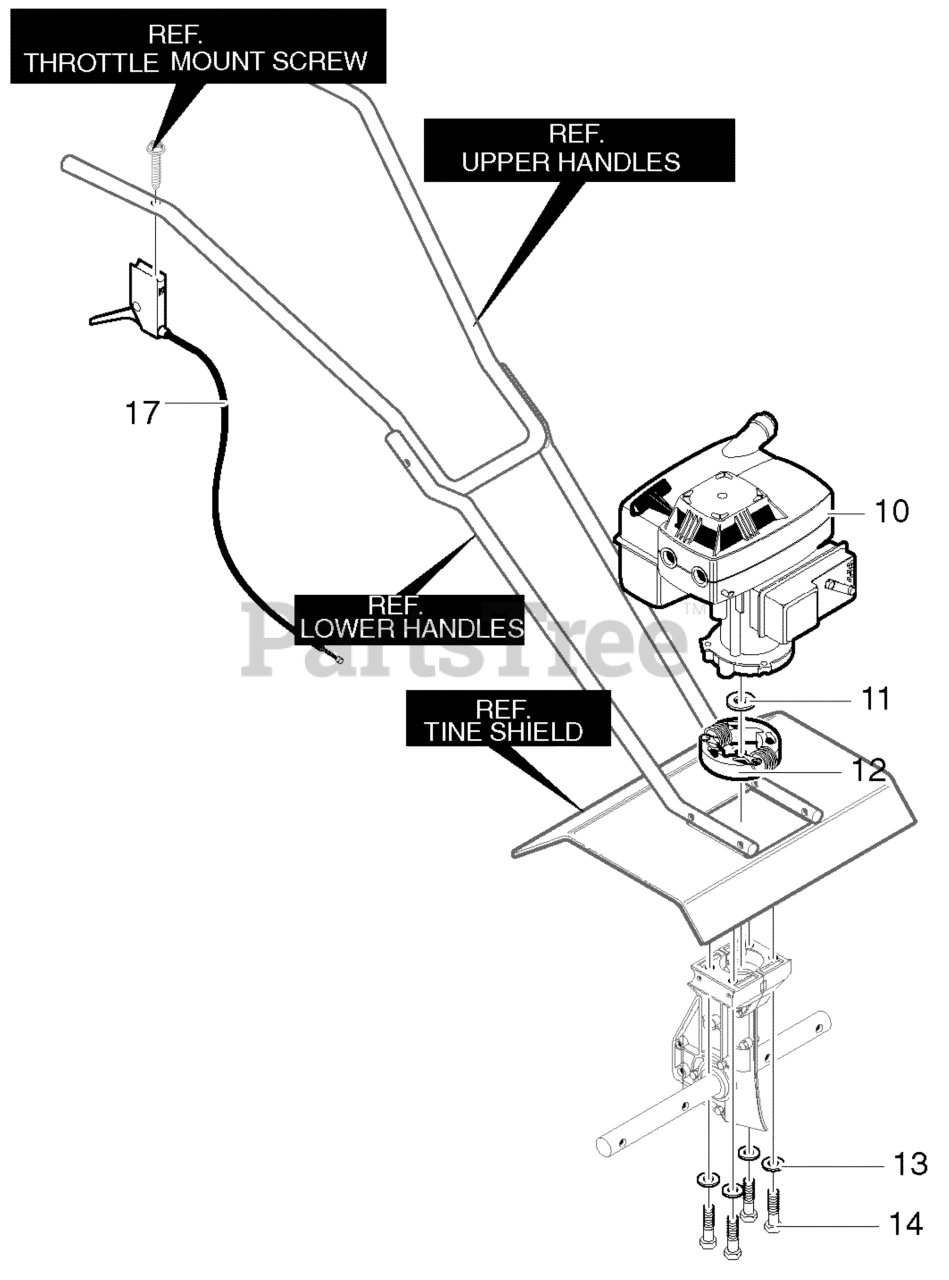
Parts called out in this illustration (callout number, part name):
10	Engine
11	Flat washer
13	Washer
14	Screw
17	Cable, Throttle
